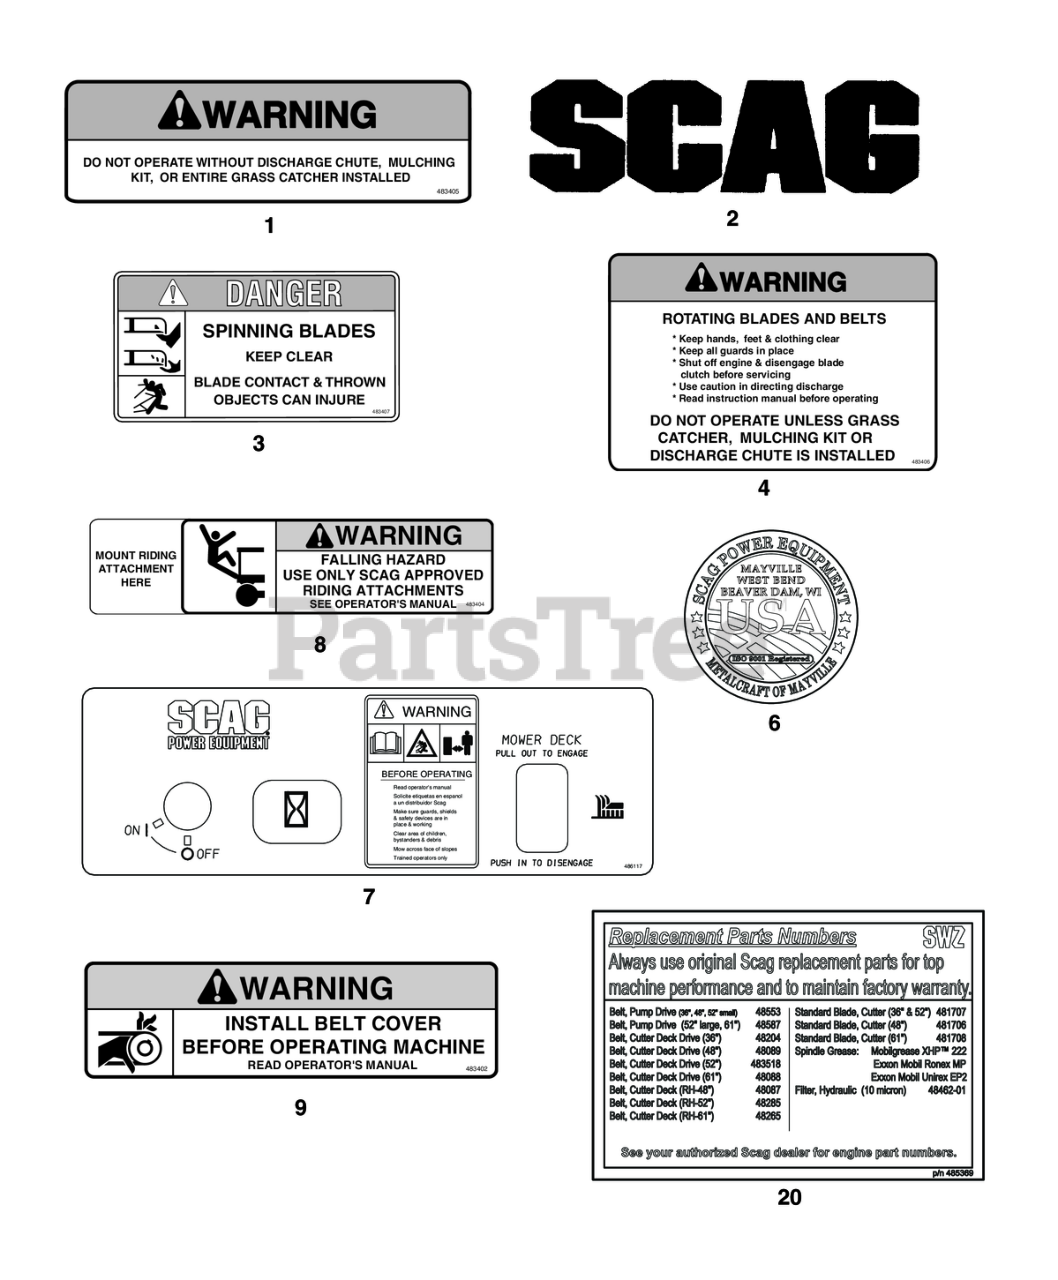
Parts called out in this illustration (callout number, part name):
1	Decal, Warning-Discharge
2	Decal, Scag Logo ( Cutter Deck)
3	Decal, Danger-Spinning Blades
4	Decal, Warning - Rotating Blades
6	Decal, Metalcraft - USA
7	Decal, Instrument Panel - Rear
8	Decal, Sulky Attachment
9	Decal, Warning - Belt Cover
20	Decal, SWZ Replacement Parts
